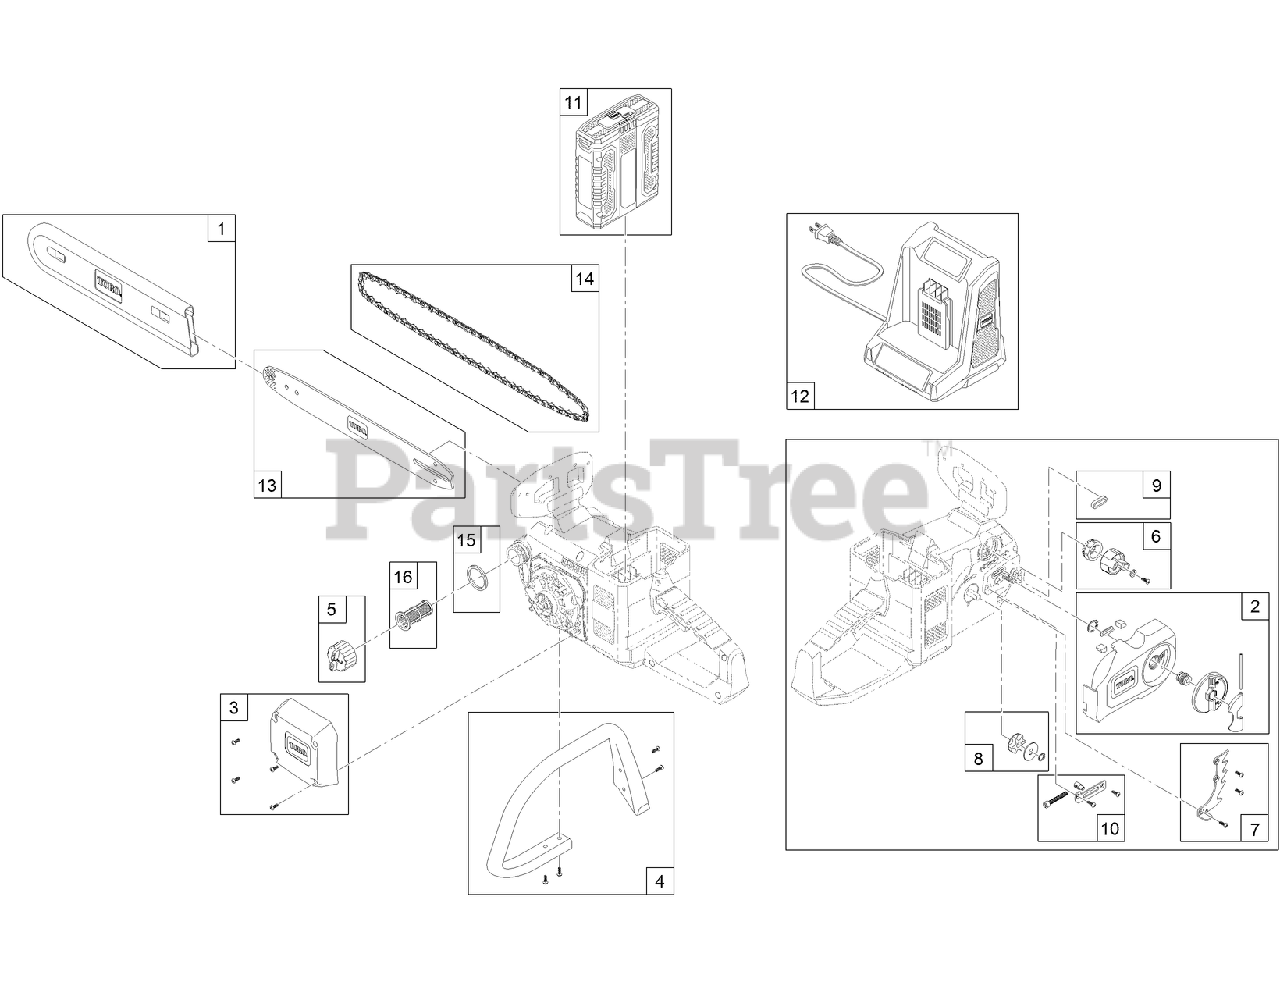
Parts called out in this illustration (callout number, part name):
1	SLEEVE-BAR/CHAIN
2	CHAIN Bar PANEL ASM
3	COVER-MOTOR
5	CAP-OIL, BAR
6	KNOB-ADJUSTER, Bar AND CHAIN
7	BUCKING TEETH BRACKET ASM
8	SPROCKET-DRIVE, CHAIN
9	GASKET-OIL, BAR/HOUSING
10	ADJUSTER-Bar PIN AND SCREW
11	BATTERY-40V MAX
12	CHARGER-40V MAX
13	Bar-REPLACEMENT
14	CHAIN-REPLACEMENT
15	GASKET-OIL CAP, BAR
16	Strainer-Oil, Bar
